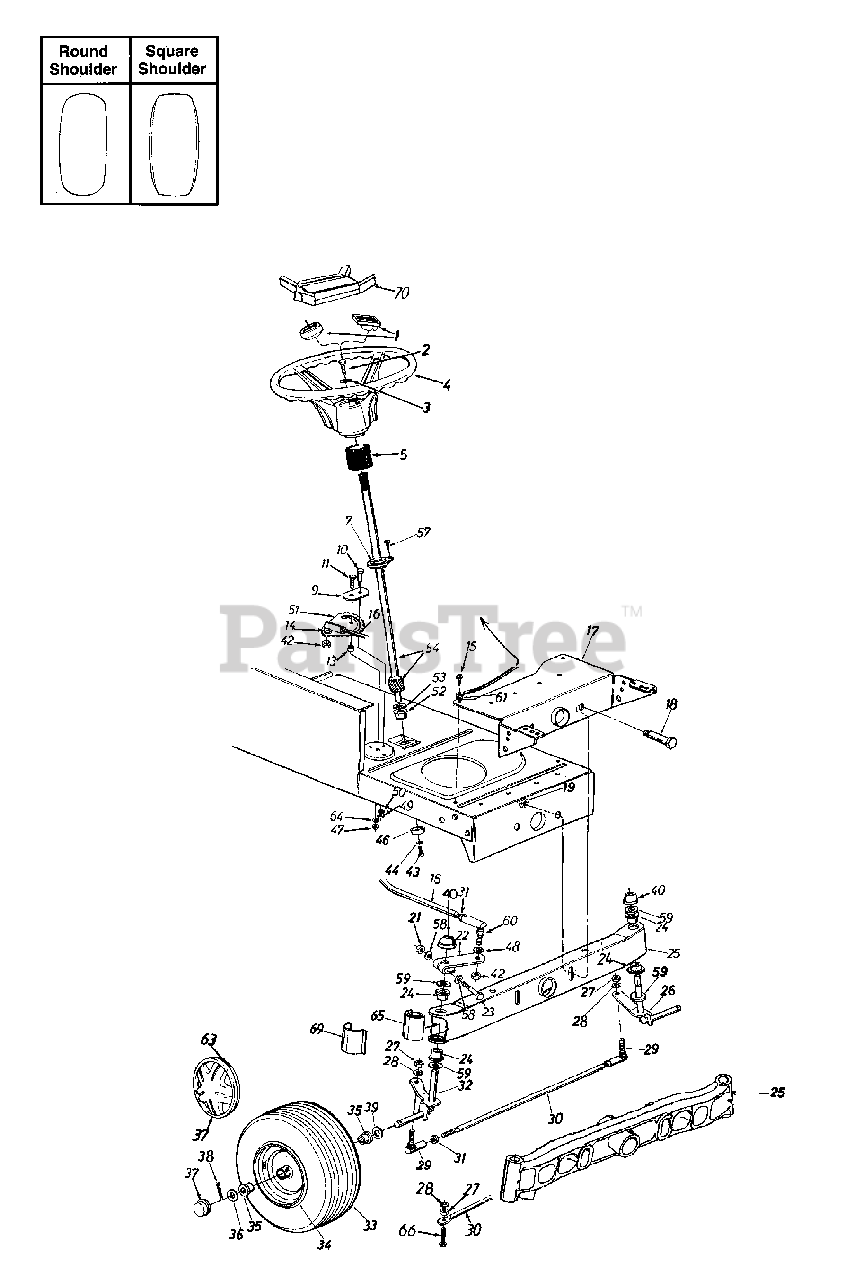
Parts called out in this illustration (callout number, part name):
1	Steering Wheel Cap
2	Hex Bolt 5/16-18 x 1" Lg.
3	Belleville Wash. .345" I.D.
4	Steering Wheel (3 Spoke)
5	Steering Bellow-4.5"
7	Flange Bearing .628" I.D. x 1.36 O.D.
9	Retainer Plate
10	Shoulder Bolt .437" Dia. x.35 Lg. 5/16-18 Thd.
11	Hex Bolt 3/8-24 x 1.0" Lg. (Gr. 5)
13	Spacer .380" I.D. x .625" O.D.
14	L-Wash. 3/8" I.D. (H.D.)
15	Hex Wash. Hd. Self-Tap Scr.
16	Steering Drag Link
18	Shoulder Bolt
19	Flanged L- Nut 3/8-16 Thd.
21	Hex L-Nut 5/16-24 Thd.
22	Steering Arm Front Axle
23	Hex Bolt 5/16-24 x 2.00" Lg.
24	Hex Flg. Brg. .632 I.D.
26	Front Axle Ass'y.-L.H. - 15" x 6" (Round/Square Shoulder)
27	Hex Nut 3/8-24 Thd.
28	L-Wash. 3/8" I.D.
29	Ball Joint 3/8-24 Thd.
30	Tie Rod (Adjustable)
31	Hex Jam Nut 3/8-24 Thd.
32	Front Axle Ass'y.-R.H. - 15" x 6" (Round/Square Shoulder)
36	Fl-Wash. .635 I.D. x 1.59" O.D.
37	Front Wheel Hub Cap
38	Cotter Pin 1/8" Dia. x 1.25"
39	Fl-Wash. .640" I.D. x 1.24" O.D.
40	Push Cap 5/8" Dia. Rod
42	Hex Jam Nut 3/8-24 Thd.
43	Hex Patch Bolt 5/16-18 x .62"
46	Cap
47	Hex Cent. L-Nut 3/8-24 Thd.
48	L-Wash. 3/8" I.D.
49	Hex Cent. L-Nut 5/16-18 Thd.
50	L-Wash. 5/16" I.D.
51	Steering Gear Segment
52	Hex Flg. Brg. .634 I.D.
53	Fl-Wash. (Hardened)
54	Steering Shaft
57	Oval Hd. Cr.-Sunk Scr.
58	Wave-Wash. .32" I.D. x .62" O.D.
59	Fl-Wash. (Hardened)
60	Drag Link Ball Joint 7/16-20 Thd.
63	Spring Clip
64	Bell-Wash. .39" I.D. x 1.38" O.D.
65	Pivot Bar End Cap
66	Hex Bolt 3/8-24 x 1.5" Lg. (Gr. 5)
69	Axle Cap
70	Steering Wheel Insert
